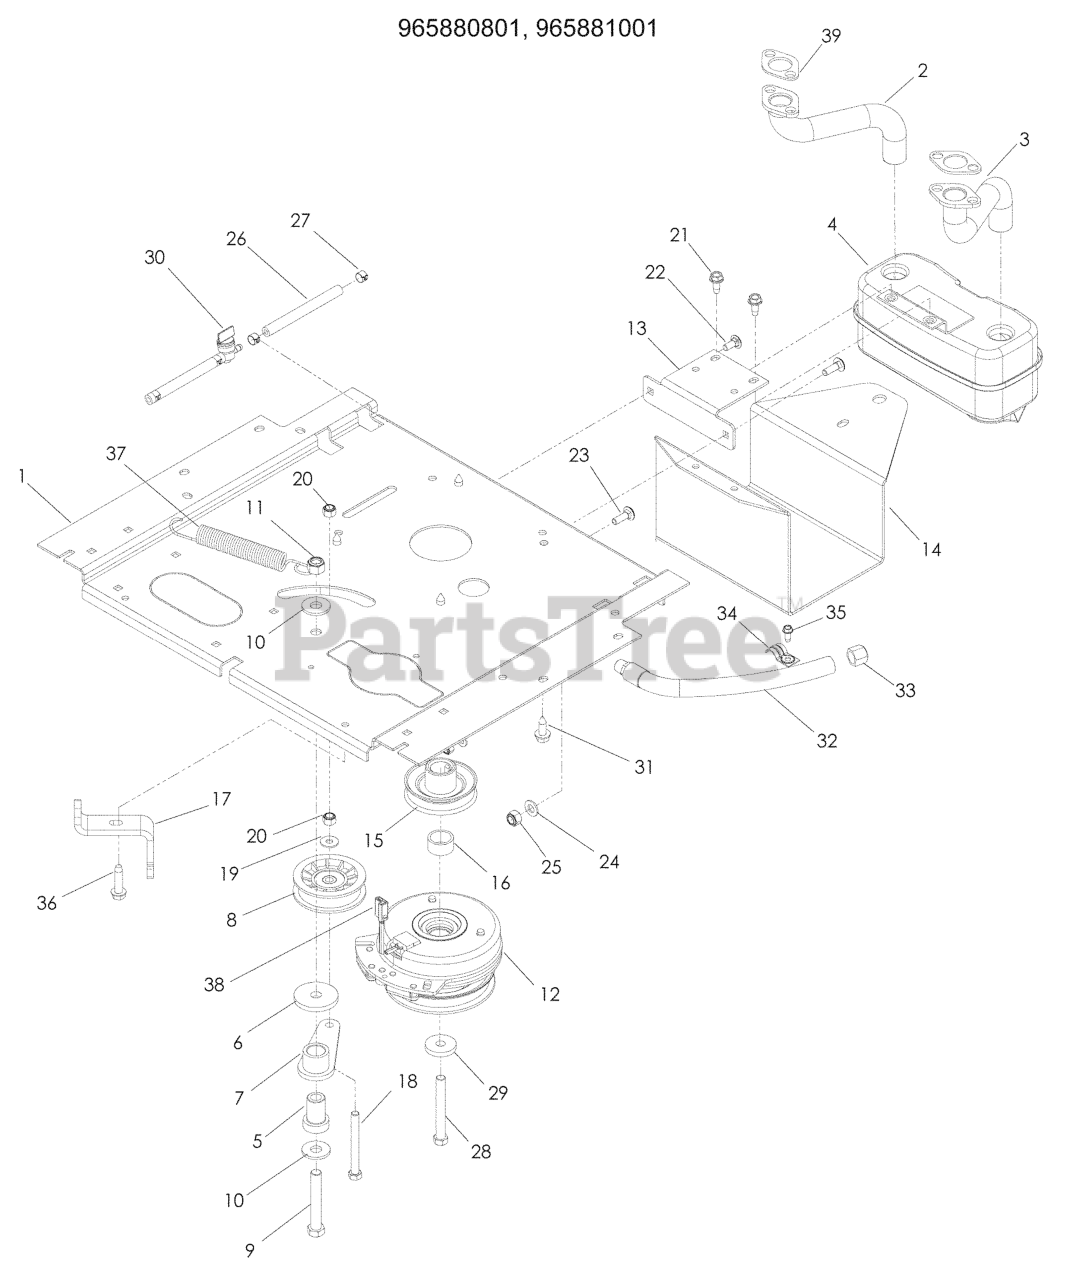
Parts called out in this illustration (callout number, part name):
1	PLATE, ENGINE, BLACK
2	RP.EXHAUST.TUBE.LH.BS/TWIN
3	EXHAUST.TUBE.RH.BS/TWIN
4	MUFFLER ASM TWIN
5	IDLER SPINDLE
6	HEAVY WASHER
7	RP.IDLER ARM WELDMENT
8	PULLEY, IDLER RAKE & ZTR
9	HCS 1/2C X 3 1/4
10	WASH USS FLAT 1/2
11	NUT 1/2-13 HEX NYLOC ZD
12	CLUTCH, 105 FT-LBS
13	BRACKET, MUFFLER, BLACK
14	GUARD, MUFFLER, BLACK
15	PULLEY, ENGINE
16	T & B SPACER
17	STOP, CLUTCH BLK
18	HCS 3/8-16X3 1/2 GR5
19	WASHER 5/16 FLAT
20	NUT 3/8-16 NYLOC
21	BOLT 5/16-18 X 3/4
22	BOLT 5/16C X 3/4" CARRIAGE
23	RHSNB 5/16C X 1
24	FLAT WASHER 5/16 SAE
25	NUT 5/16 NYLOC
26	FUEL LINE 5"
27	HOSE CLAMP
28	HCS 7/16-20X3-1/2 GR 5 ZN
29	CLUTCH, WASHER
30	FUEL VALVE
31	HHFS 3/8-16 X 1.0 THD FORMING
32	OIL DRAIN HOSE
35	SCREW 1/4 X 5/8
36	BOLT 3/8-16 X 1 1/2 ZINC CLEAR
37	SPRING, DECK DRIVE
38	CLUTCH HARNESS
39	EXHAUST GASKET - KAW
